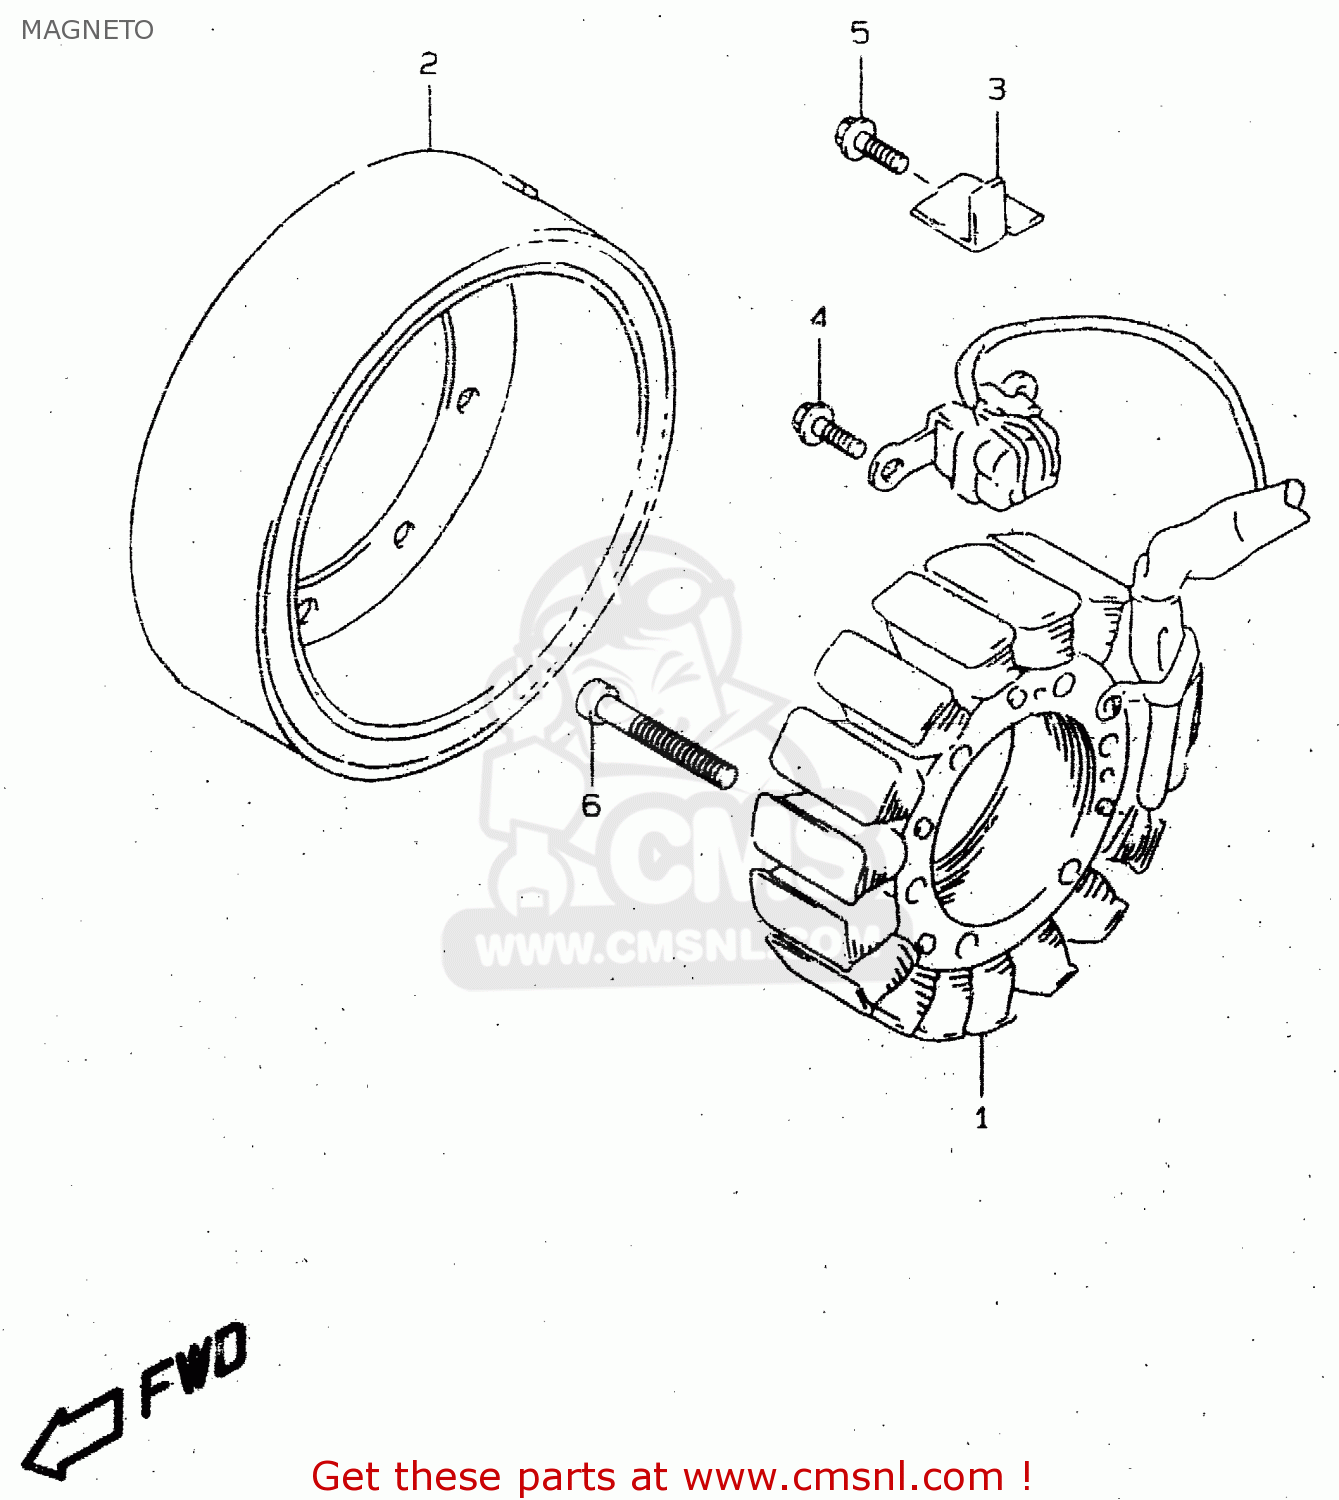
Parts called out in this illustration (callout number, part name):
1	STARTER ASSY
2	ROTOR ASSY
3	CLAMP,MAGNETO LEAD NO.1
4	BOLT
5	BOLT
6	BOLT
